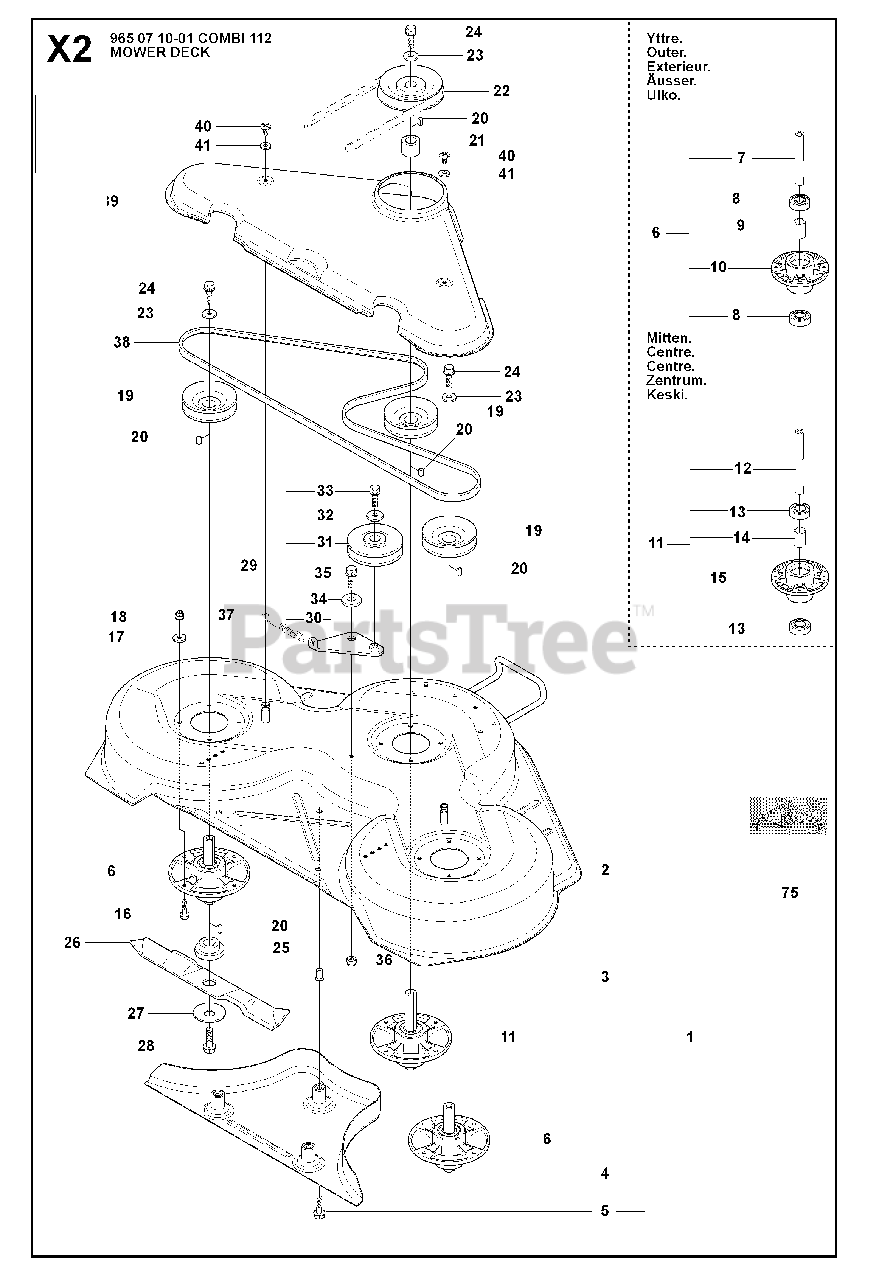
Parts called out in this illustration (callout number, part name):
6	RP SPINDLE ASSY
10	BEARING HOUSING
11	RP SPINDLE ASSY
15	BEARING HOUSING
17	WASHER BRB 8.4X17
18	LOCKNUT M8
26	BLADE
29	BELT TENSIONER ASSY
30	BELT TENSIONING ARM
34	WASHER
36	LOCKNUT M8
38	BELT
44	LOCKNUT M8
51	LOCKNUT M8
52	PARALLEL RODY ASSY
58	CLUTCH ROD ASSY
67	LOCKNUT M8
68	DECK ROLLER, FRONT
70	RETAINING RING SGA 15
73	WASHER
74	LOCKNUT M6
